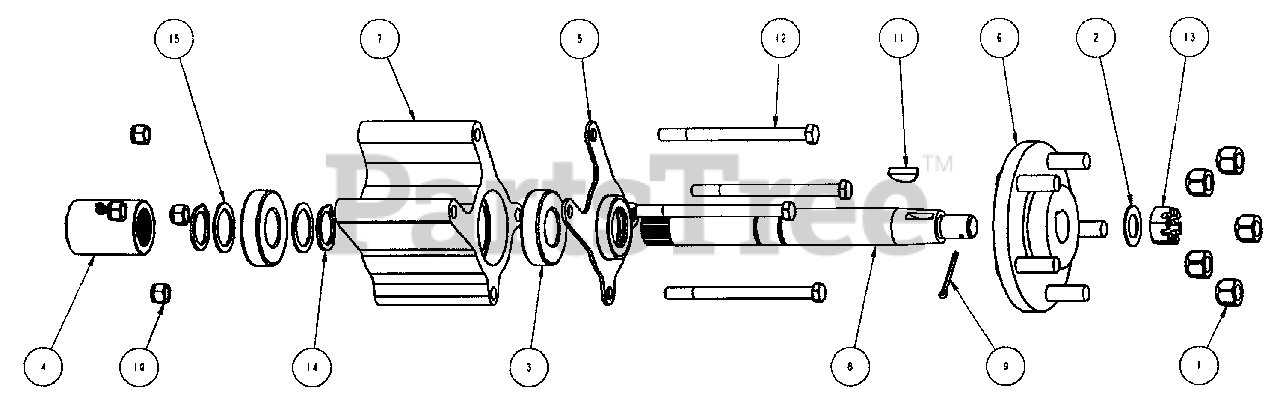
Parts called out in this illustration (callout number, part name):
1	LUG NUT 1/2-20, YZ
2	FLW, .77 X 1.31 X.06 YZ
3	BEARING 30MM X 62MM
4	ASSY., COUPLING W/LUBE FITTING
5	ASSEMBLY, PLATE/SEAL
6	REAR WHEEL HUB
7	CVT AXLE SUPPORT
8	AXLE, CVT
9	COTTER PIN, 1/8 X 3/4 YZ
10	HNYL, 3/8-16, YZ
11	WOODRUFF KEY 808
12	H HCS, 3/8-16 X 5.5 - YZ
13	HEX NUT, 7/8-14, YZ
14	SNAP RING, 30MM, HD
15	FLAT WASHER, 1 3/16 X 1 5/8 X .06
